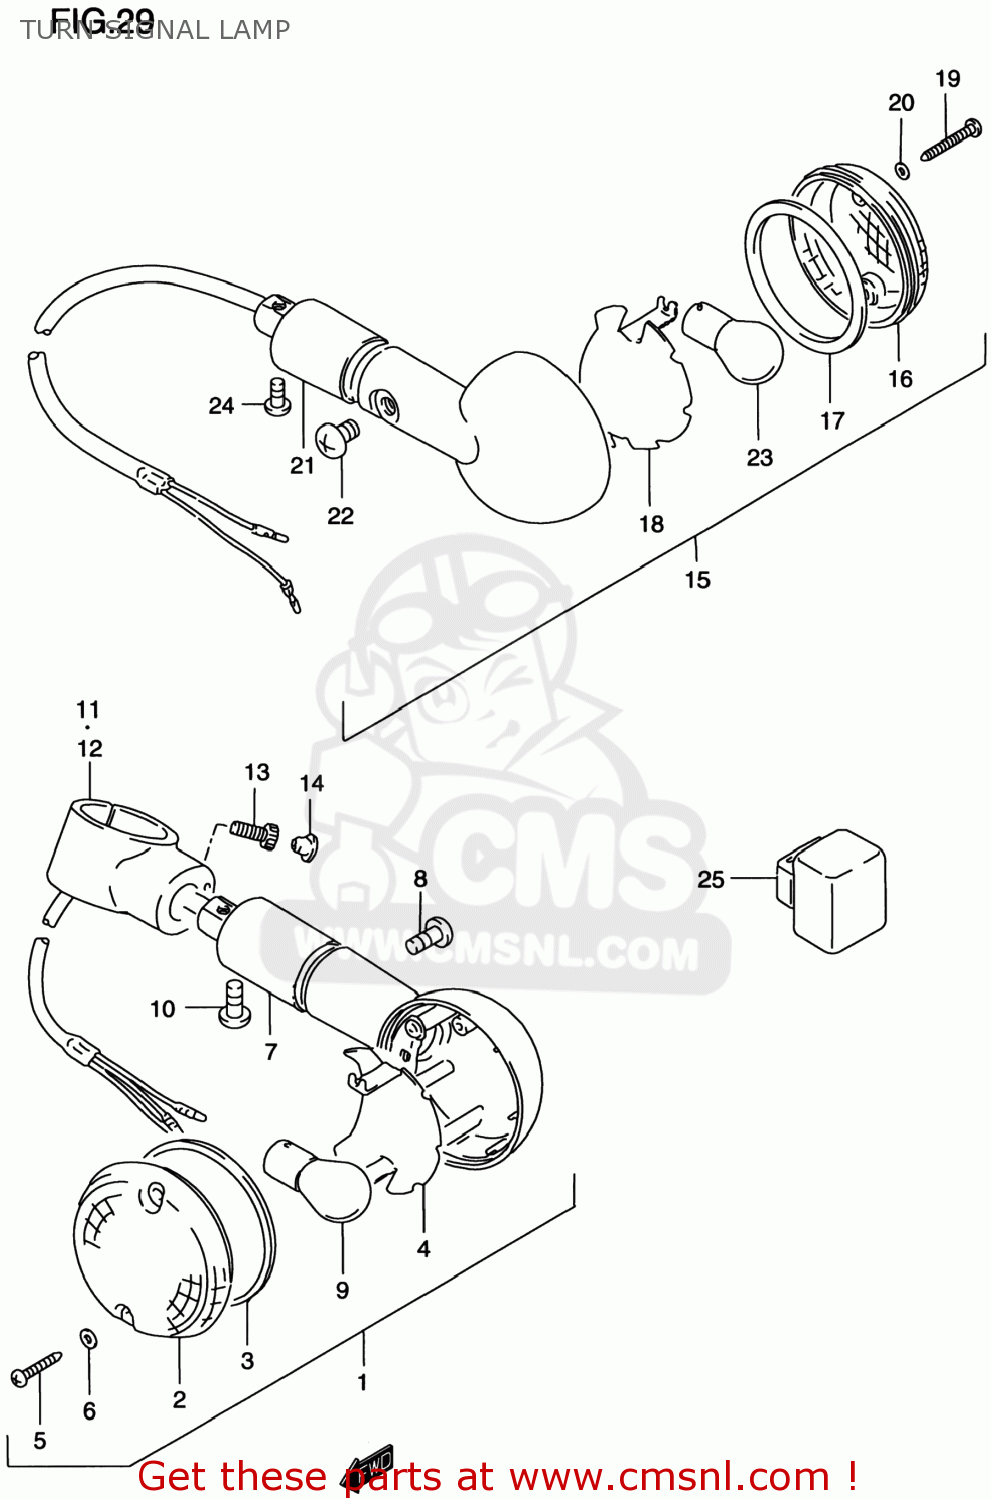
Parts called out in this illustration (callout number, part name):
1	LAMP ASSY,FR TURN SIGNAL
2	LENS
3	GASKET (NAS)
4	REFRECTOR
5	SCREW
6	GASKET (NAS)
7	STAY,TURNSIGNAL LAMP
8	SCREW
9	BULB(12V21/5W,BF141-49642A)
10	SCREW
11	BRACKET,FR TURNSIGNAL LAMP,R
12	BRACKET,FR TURNSIGNAL LAMP,L
13	BOLT
14	CAP(OD:10)
15	LAMP ASSY,FR TURN SIGNAL
16	LENS
17	GASKET (NAS)
18	REFRECTOR
19	SCREW
20	GASKET (NAS)
21	STAY,TURNSIGNAL LAMP
22	SCREW
23	BULB(12V21W)
24	SCREW
25	RELAY ASSY
